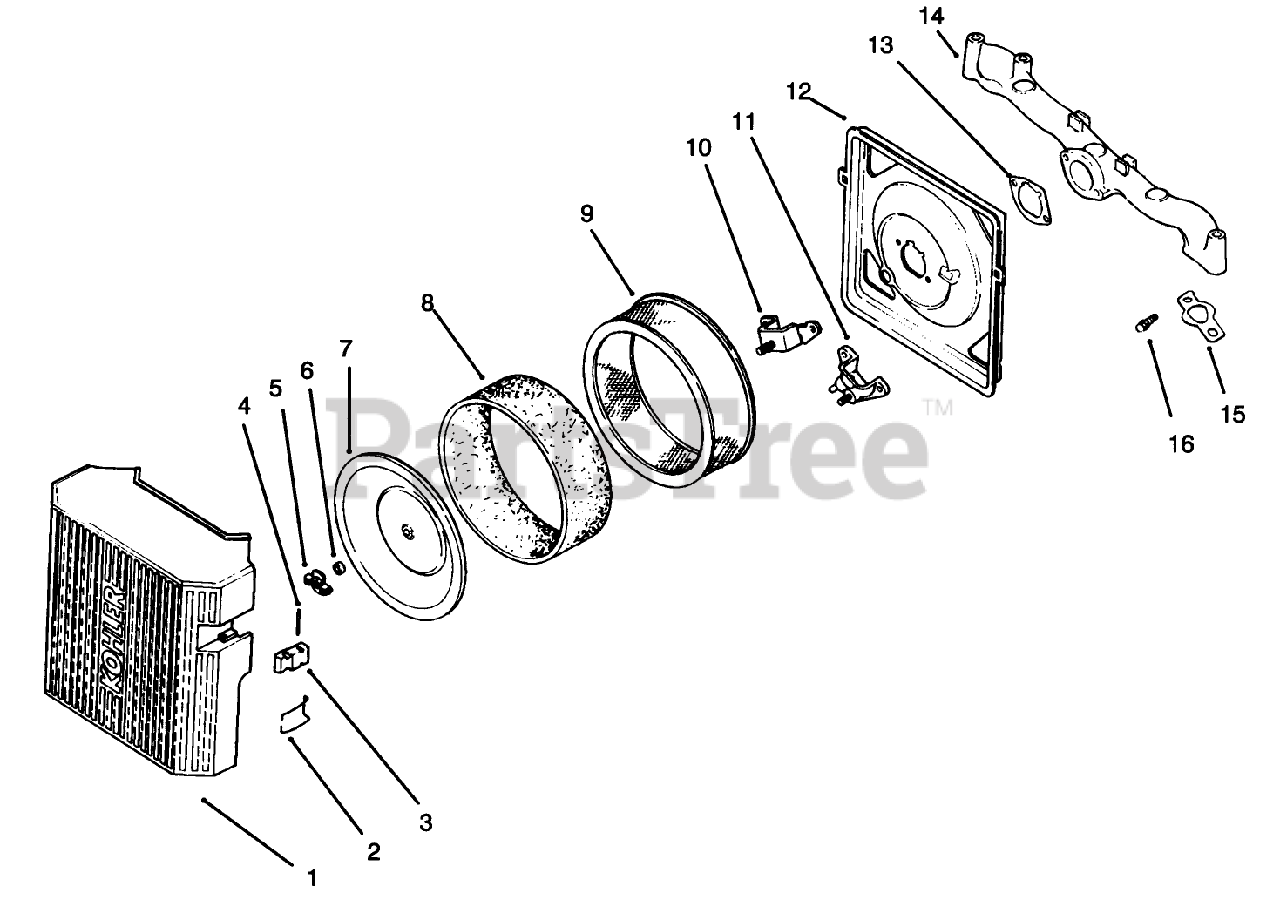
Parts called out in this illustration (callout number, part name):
1	Kit-A/C Cover INCL 2-4 (Only On: 72103;
2	Spring-Latch (Only On: 72103)
3	Latch-Lever (Only On: 72103)
4	Pin-Latch Lever (Only On: 72103)
5	Nut-Wing
6	Seal-Air Intake (Only On: 72103)
7	Cover-Inner Air Cleaner
8	Element-Precleaner
9	Element-Air Cleaner
10	Cup-Fuel Spitback (Only On: 72103)
11	Gasket-Fuel Spitback Cup (Only On: 72103, 72083)
12	Base-Air Cleaner (Only On: 72103)
13	Gasket-A/C Base (Only On: 72103, 72083)
14	Manifold-Intake (Only On: 72103)
15	Gasket-Intake Manifold
